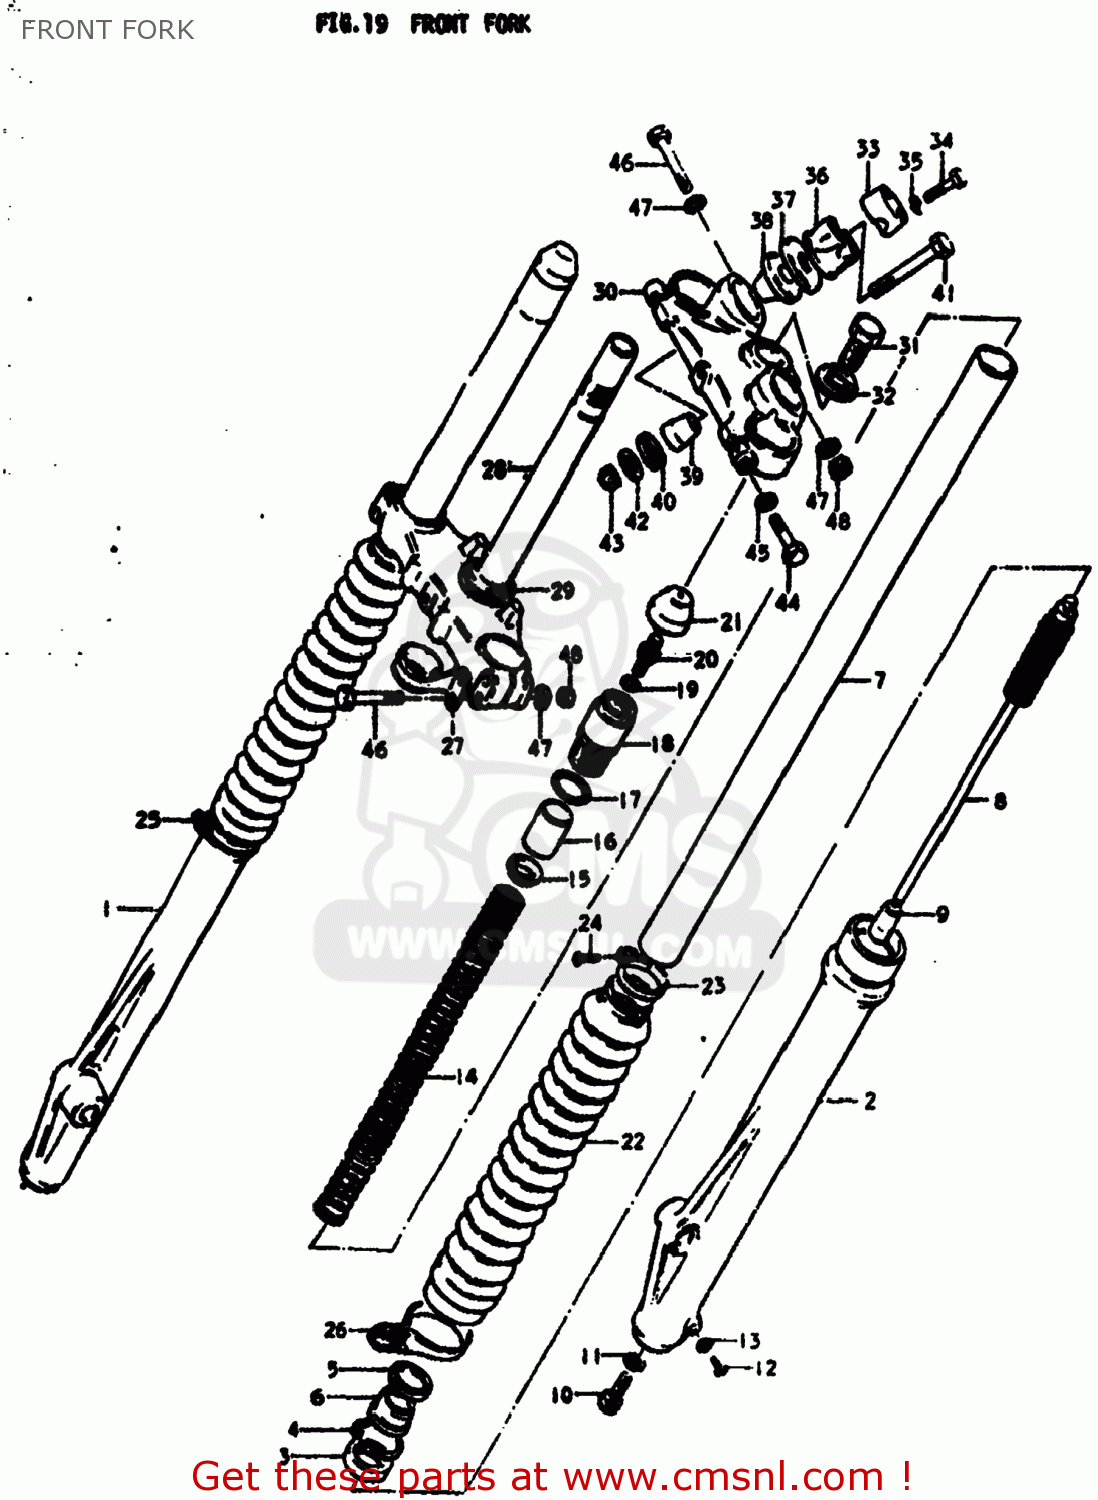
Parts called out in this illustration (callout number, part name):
1	TUBE,OUTER,RIGHT
2	TUBE,OUTER,LEFT
3	CIRCLIP,FORK OIL SEAL
4	CIRCLIP,FORK OIL SEAL
5	GUIDE.FORK DUST
6	DUST SEAL,FRONT FORK
7	TUBE,FORK,INNER
8	CYLINDER,FRONT FORK
9	PIECE,OIL LOCK
10	BOLT,FORK CYLINDER(10X25)
11	GASKET (NAS)
12	SCREW
13	GASKET,DRAIN,PLUG (NAS)
14	SPRING
15	GUIDE,FRONT FORK SPRING C
16	SPACER,SPRING
17	O RING
18	CAP ASSEMBLY,FORK
19	O RING
20	VALVE
21	CAP
22	BOOT
23	BAND,BOOT
24	SCREW
25	BAND,FRONT FORK COVER
26	BAND,FRONT FORK COVER
27	GUIDE,CABLE
28	STEM,STEERING
29	RACE,STEERING OUTER LWR
30	HEAD,STEERING STEM
31	BOLT
32	WASHER
33	HOLDER,HANDLEBAR
34	BOLT
35	LOCK WASHER
36	HOLDER,HANDLEBAR
37	COVER, UPPER
38	CUSHION
39	RUBBER, LOWER
40	SPACER,STEERING DAMPER
41	BOLT,HANDLE HOLDER
42	WASHER
43	NUT 12MM
44	BOLT
45	LOCK WASHER
46	BOLT 8X55
47	WASHER
48	NUT
